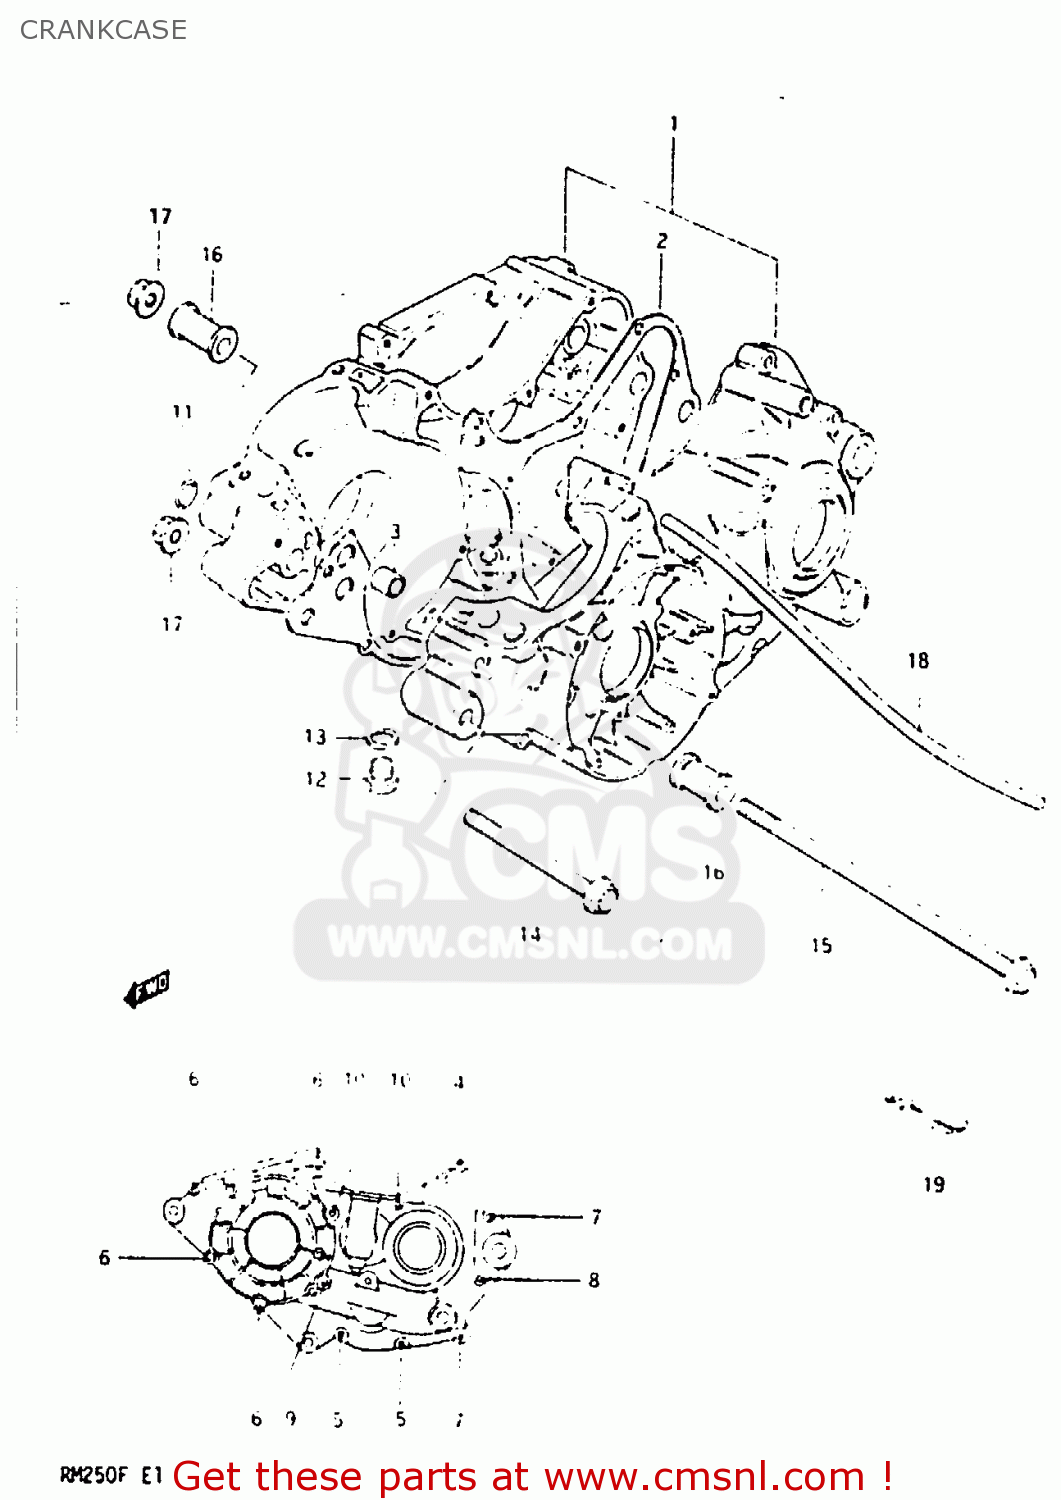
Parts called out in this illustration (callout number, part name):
1	CRANKCASE SET
2	GASKET,CRANKCASE (MCA)
3	PIN
4	SCREW
5	SCREW
6	SCREW
7	SCREW (6*50)
8	SCREW
9	SCREW (6*60)
10	SCREW
11	O RING(D:1.9,ID:13.8)
12	PLUG
13	GASKET(14X19.2X2) (NAS)
14	BOLT(8X100)
15	BOLT(8X225)
16	SPACER,ENGINE MOUNT
17	NUT
18	HOSE
19	CLAMP
